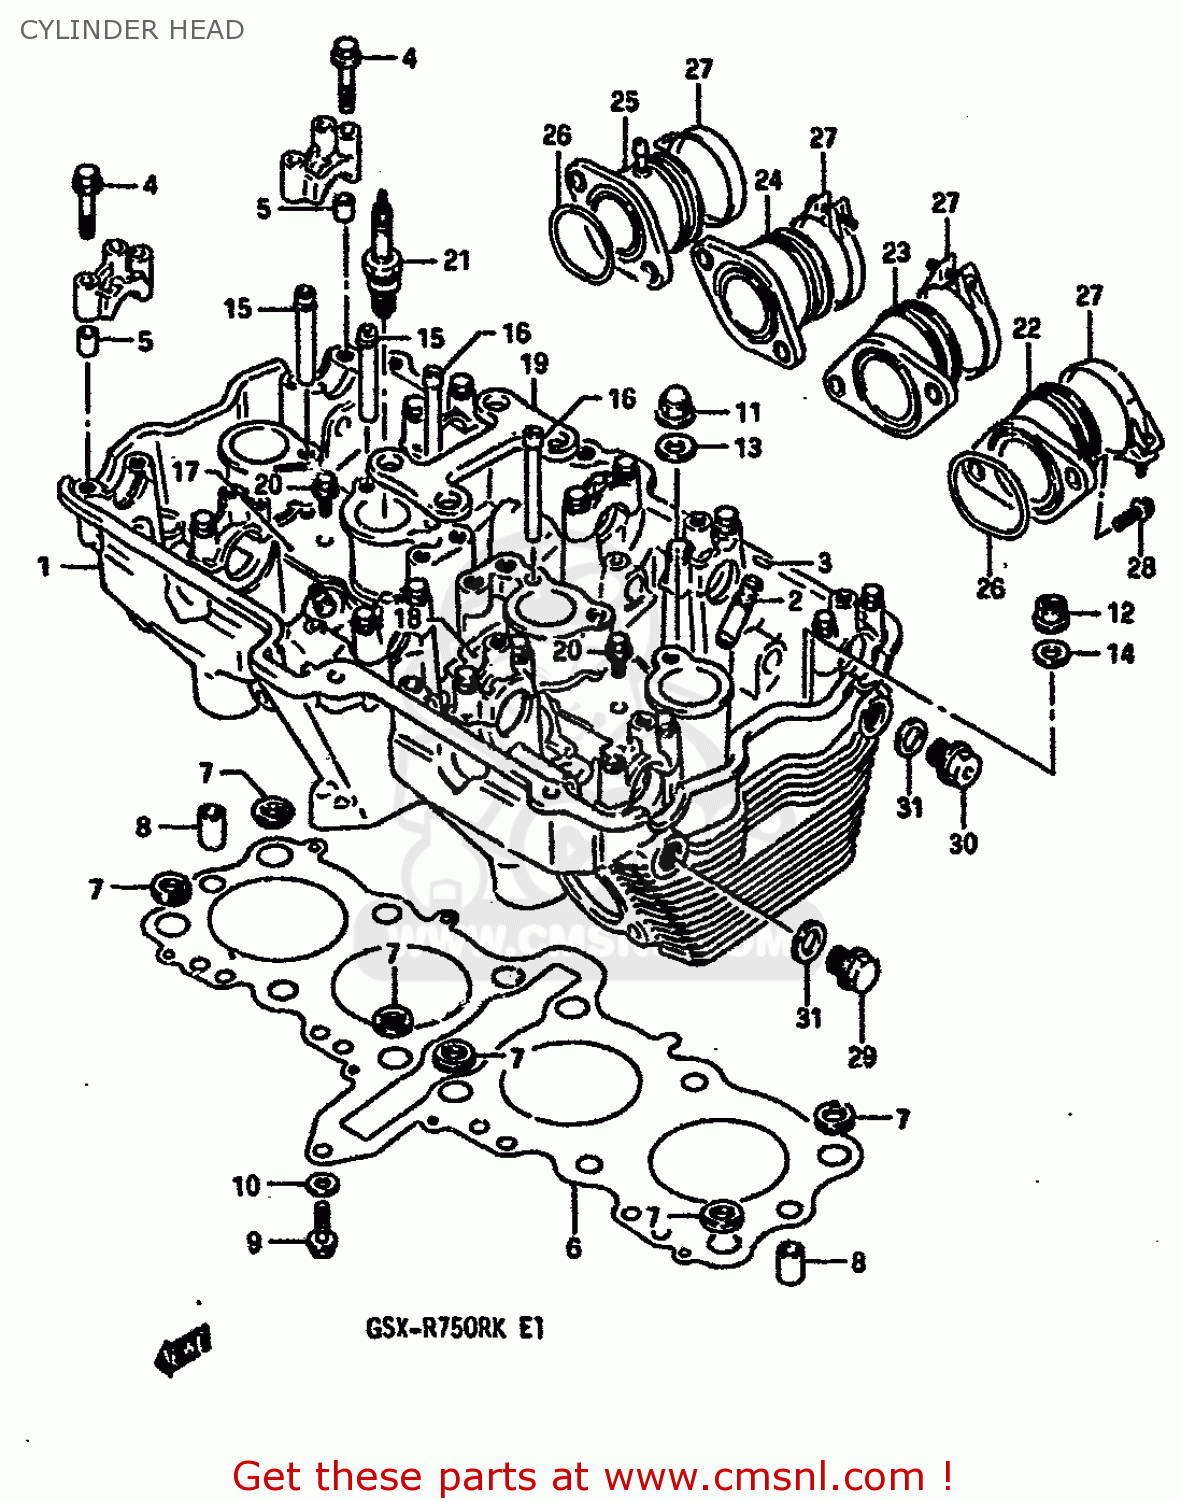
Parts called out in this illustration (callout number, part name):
1	HEAD ASSY,CYLINDER
2	GUIDE,VALVE
3	RING,SNAP
4	BOLT(6X39)
5	PIN(6.2X8X11)
6	GASKET,CYLINDER HEAD
7	O RING,HEAD GASKET
8	PIN
9	BOLT 6X30
10	WASHER (6.2X14X2)
11	NUT
12	NUT
13	GASKET(10.2X20X2).3 (NAS)
14	WASHER (10.5X22X2.3)
15	PIPE,OIL NO.1
16	PIPE,OIL NO.3
17	PLATE,OIL PIPE,R
18	PLATE,OIL PIPE,L
19	PLATE,HEAD REINF
20	BOLT
21	PLUG,SPARK(CR9EK)
22	PIPE,INTAKE,LH
23	PIPE,INTAKE,ML
24	PIPE,INTAKE,MR
25	PIPE,INTAKE,RH
26	O RING(D:2.4,ID:41.7)
27	CLAMP
28	SCREW
29	PLUG
30	PLUG
31	GASKET(14X19.2X2) (NAS)
